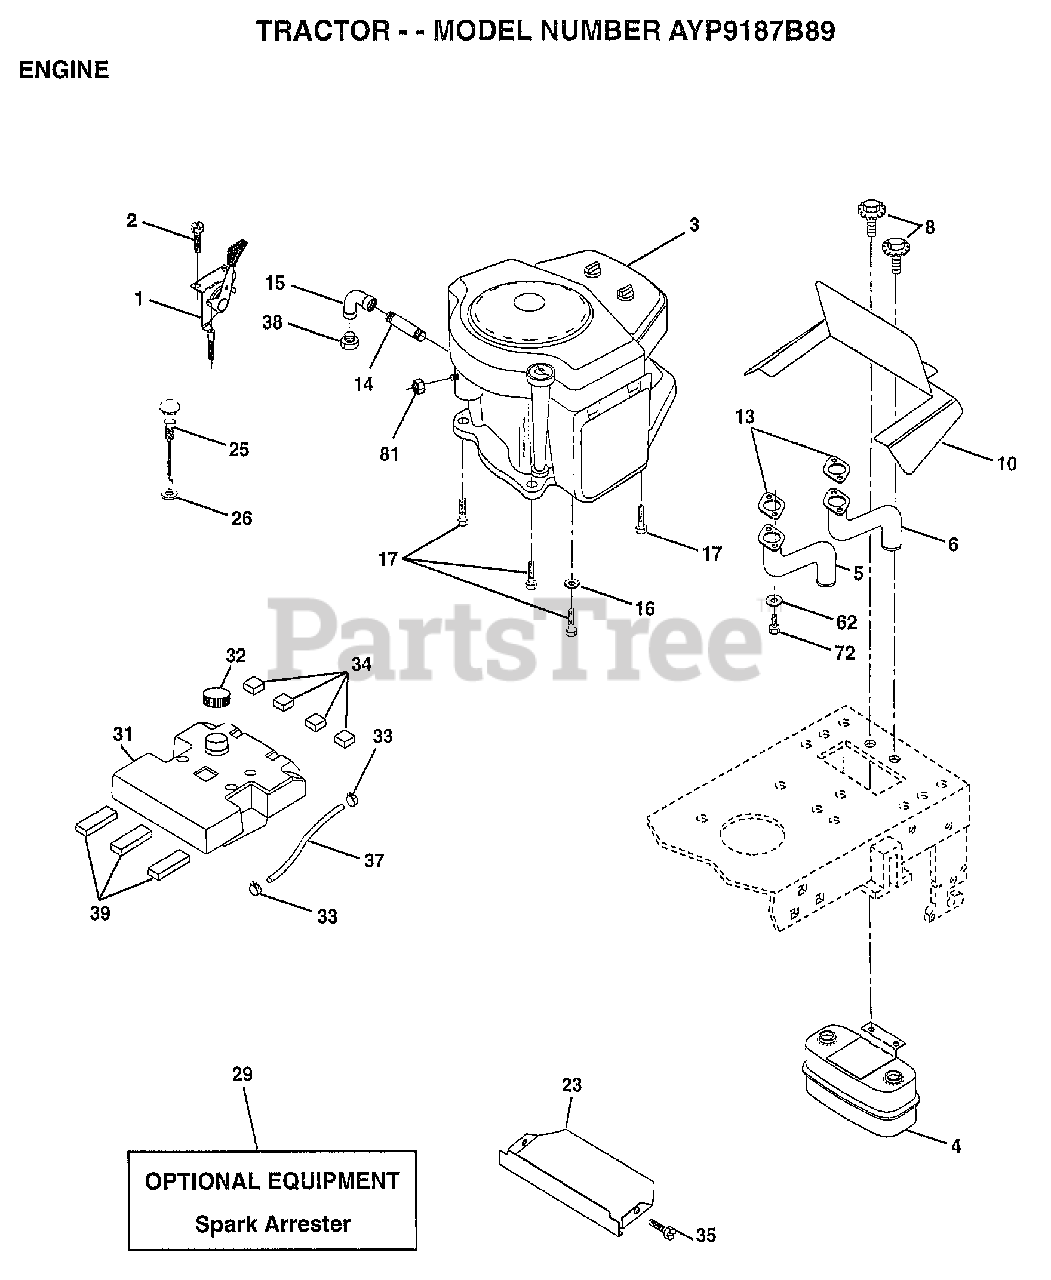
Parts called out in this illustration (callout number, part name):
1	CONTROL THROT. LH
2	SCREW LT
4	MUFFLER.TW.LOTONE
5	TUBE MANIFOLD RH
6	TUBE MANIFOLD LH
8	BOLT.5/16-18.UNC
10	SHIELD.BROWNING
13	GASKET MUFFLER
14	PIPE NIPPLE LT
15	ELBOW
16	LOCKWASHER
17	SCREW LT
23	SHIELD.BRN/DBR.GD
25	CONTROL.CHOKE.37
26	"NUT,KEPS 3/8-24IM"
31	"TANK.FUEL,3.5 GAL"
32	CAP ASM FUEL
33	HOSE CLAMP
34	PAD-SPACER LT
35	SCREW
37	FUEL LINE T
39	PAD IDLER TI
62	LOCKWASHER
72	SCREW
81	NUT
